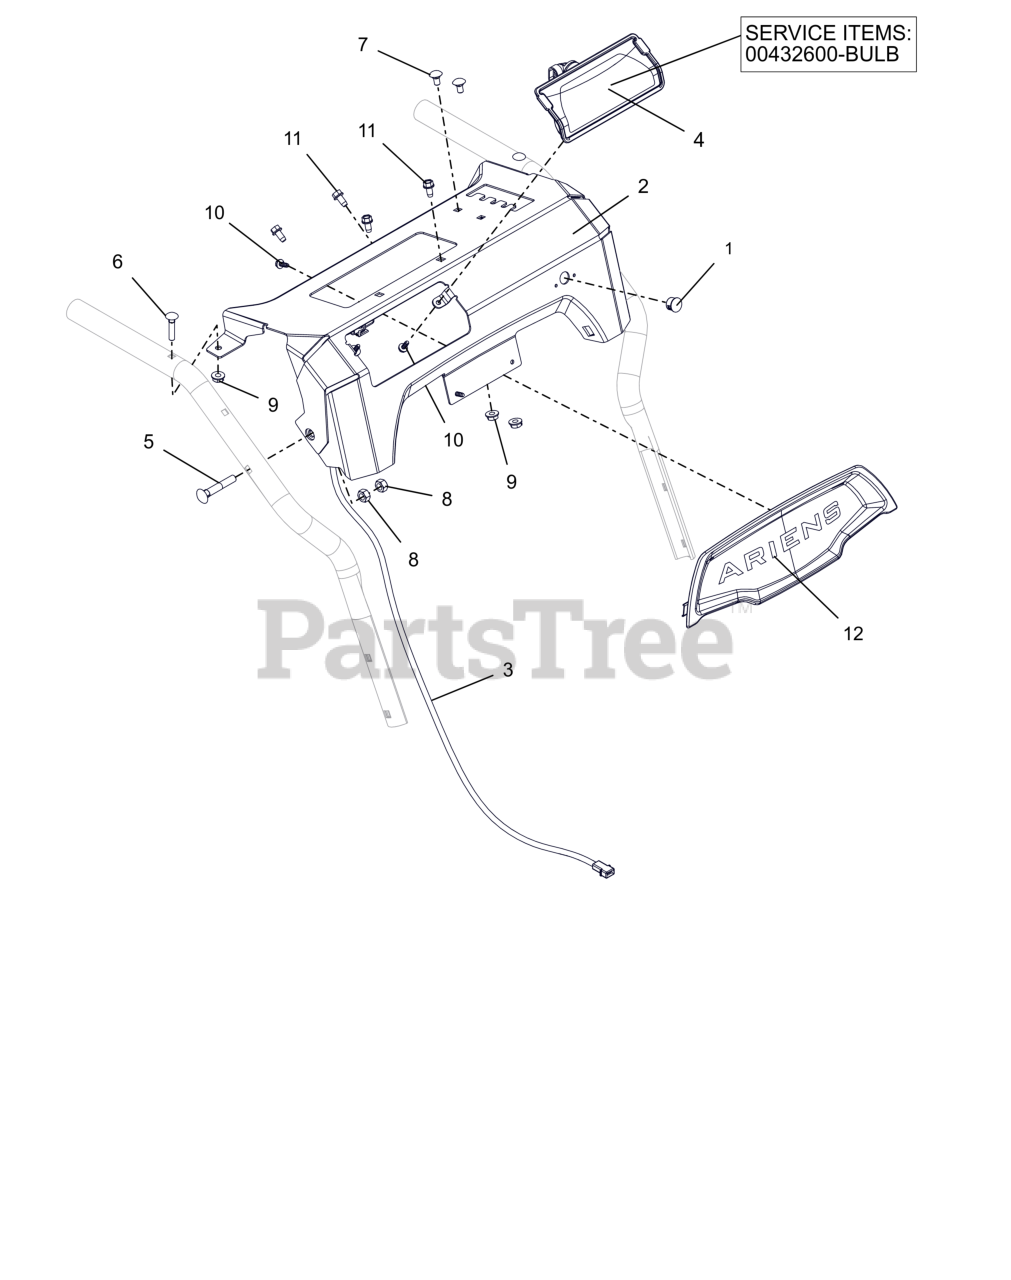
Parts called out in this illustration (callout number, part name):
1	HOLE PLUG, PLASTIC .56 HOLE
2	CTRL PANEL W/DECAL-COMP REMOTE
3	HARNESS, LIGHT - COMPACT
4	HEADLIGHT ASY, HALO 20W 2SHOT
4	BULB, LIGHT-HALOGEN 20W
5	BLT-RDHDXLSQNK .31-18X2.0 G5YZ
6	BLT-RDHDXLSQNK.25-20X1.25 G5ZC
7	BLT, RHSN .25-20X.500 G5 ZCC
8	NUT,LK-CTR .31-18 GA ZCC
9	NUT-LK-TOP-FLG .250-20 GF ZCC
10	SCR, PLASTIC #10X.50
11	SCR-TAP .25-20X.50 HWH ZCC
12	BEZEL, DASH - ARIENS SM DASH
